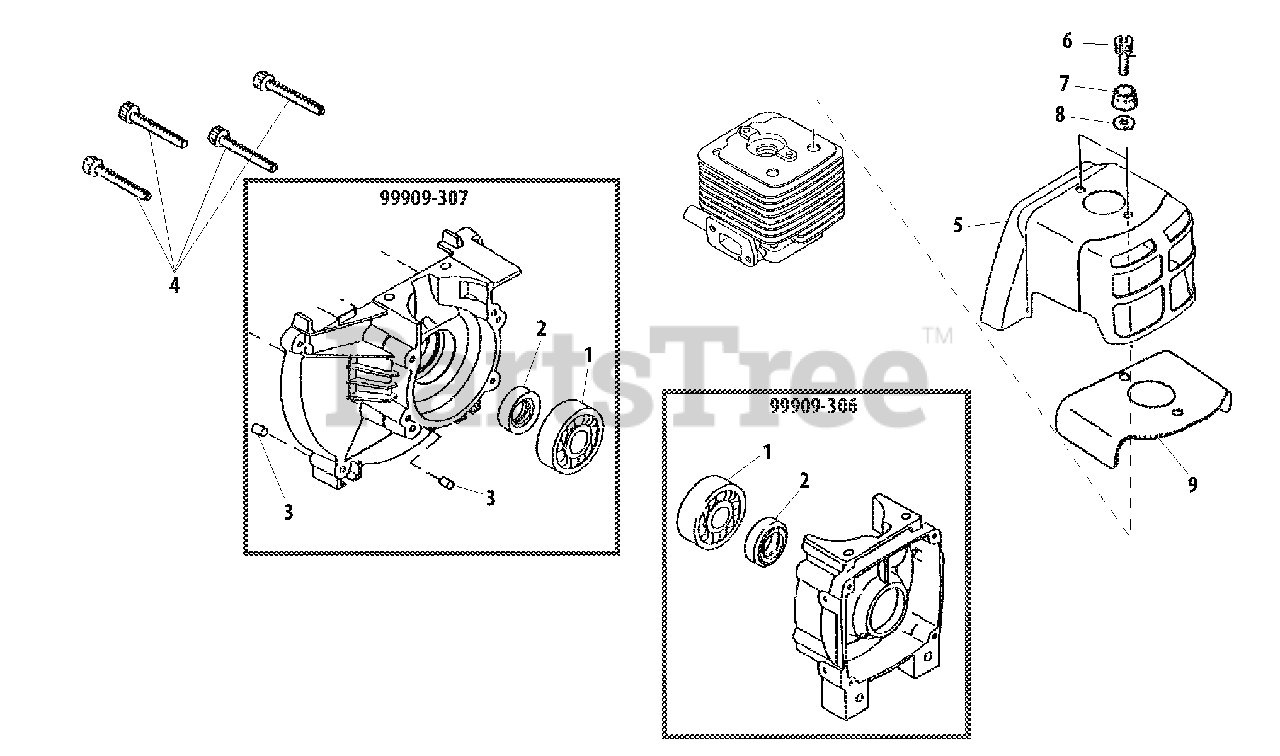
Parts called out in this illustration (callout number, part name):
1	BEARING, BALL - 6202C3
2	SEAL, OIL
3	PIN - LOCATING
4	SCREW - 5X30
5	COVER, ENGINE
6	SCREW - 5X14
7	COVER
8	WASHER
9	GASKET
99909-306	CRANKCASE ASSY - REAR
99909-307	CRANKCASE ASSY - FRONT
